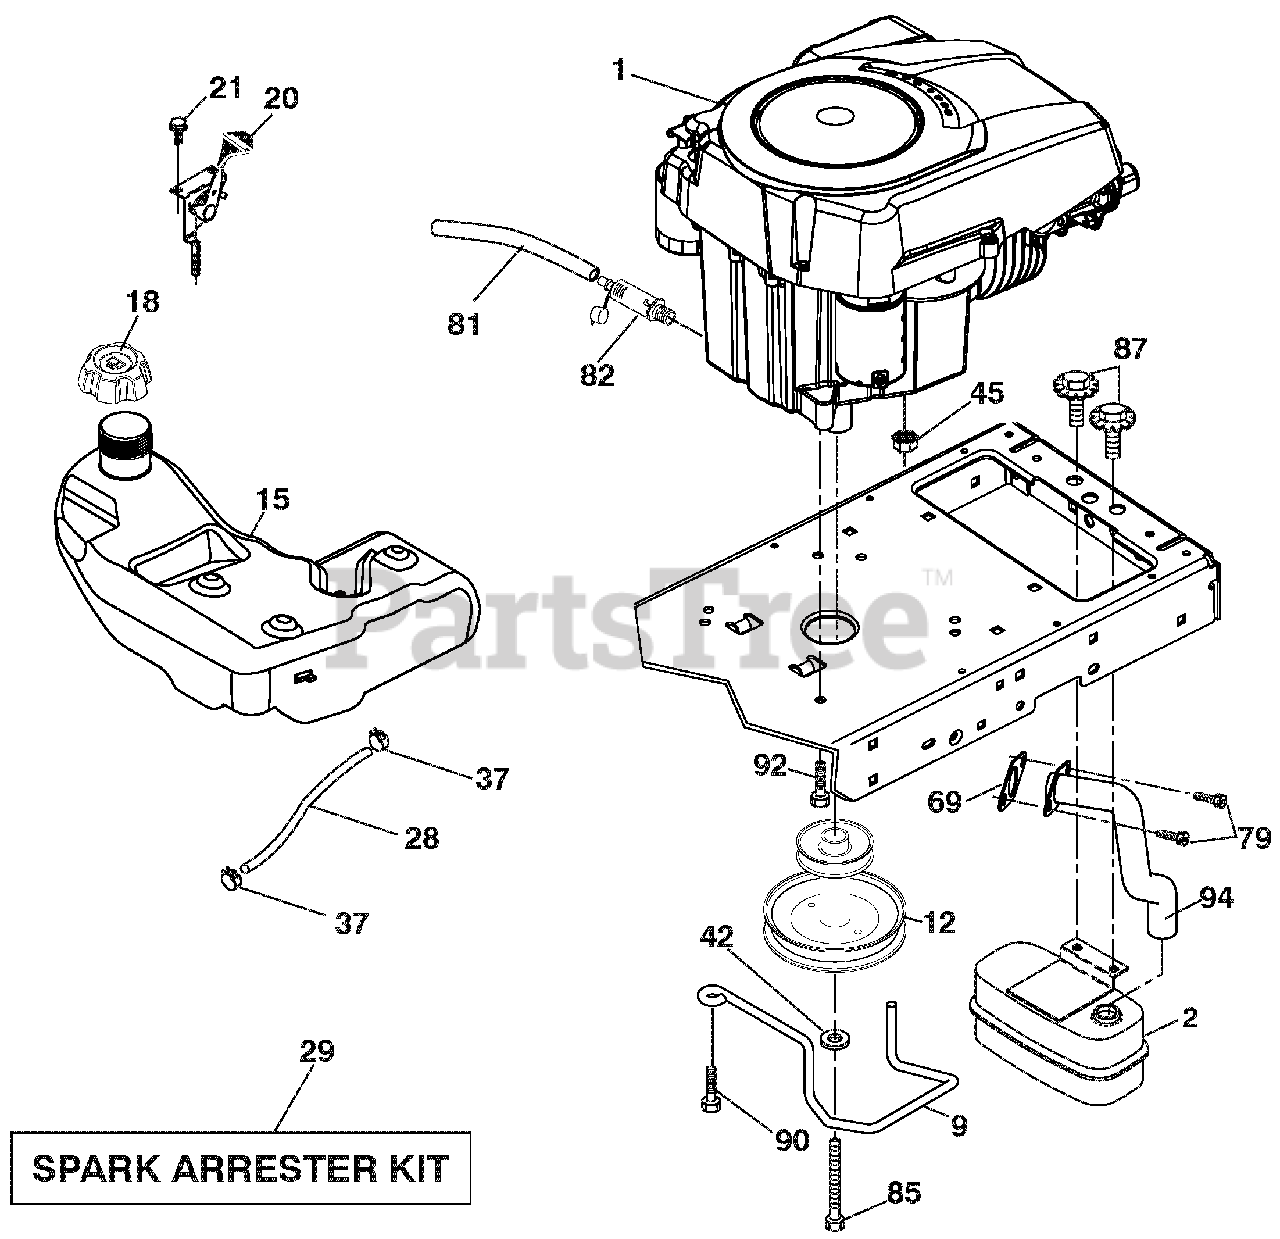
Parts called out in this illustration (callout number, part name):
2	MUFFLER.SINGLE.CYL.KOHL.COURAG
9	KEEPER.BELT.ENGINE.4.25"NSTG
12	PULLEY ENGINE
15	TANK.FUEL.SIDE-FILL.3.00 GA.
18	CAP ASM.FUEL TANK.3"BLACK
20	CONTROL.TH/CK.COBRA.BS.EEC.428
28	LINE.FUEL.64"REAR.EMIS.CA.LP
29	KIT.SPARK ARRESTOR(392390 B&S)
37	CLAMP.HOSE.BLK.
42	WASHER.LOCK.HVY HLCL.SPR.7/16
45	Nut, Keps Hex 1/4-20 unc
69	GASKET.KOHLER.SV.I.
79	SCREW.SOCKET HD.5/16-18 X .75
81	TUBE.DRAIN.OIL.EASY
82	PLUG.DRAIN.OIL.EASY
85	BOLT.HEX.7/16-20X4XGR5-1.5THR.
87	BOLT.5/16-18UNCX3/4 W/SEMS.BLK
90	SCREW.3/8-16X1.SMGML.TAP/R.BLK
92	SCREW.3/8-16 X 1.SMGML.TAP/R
94	TUBE.EXHAUST.KOHL.COURAGE
